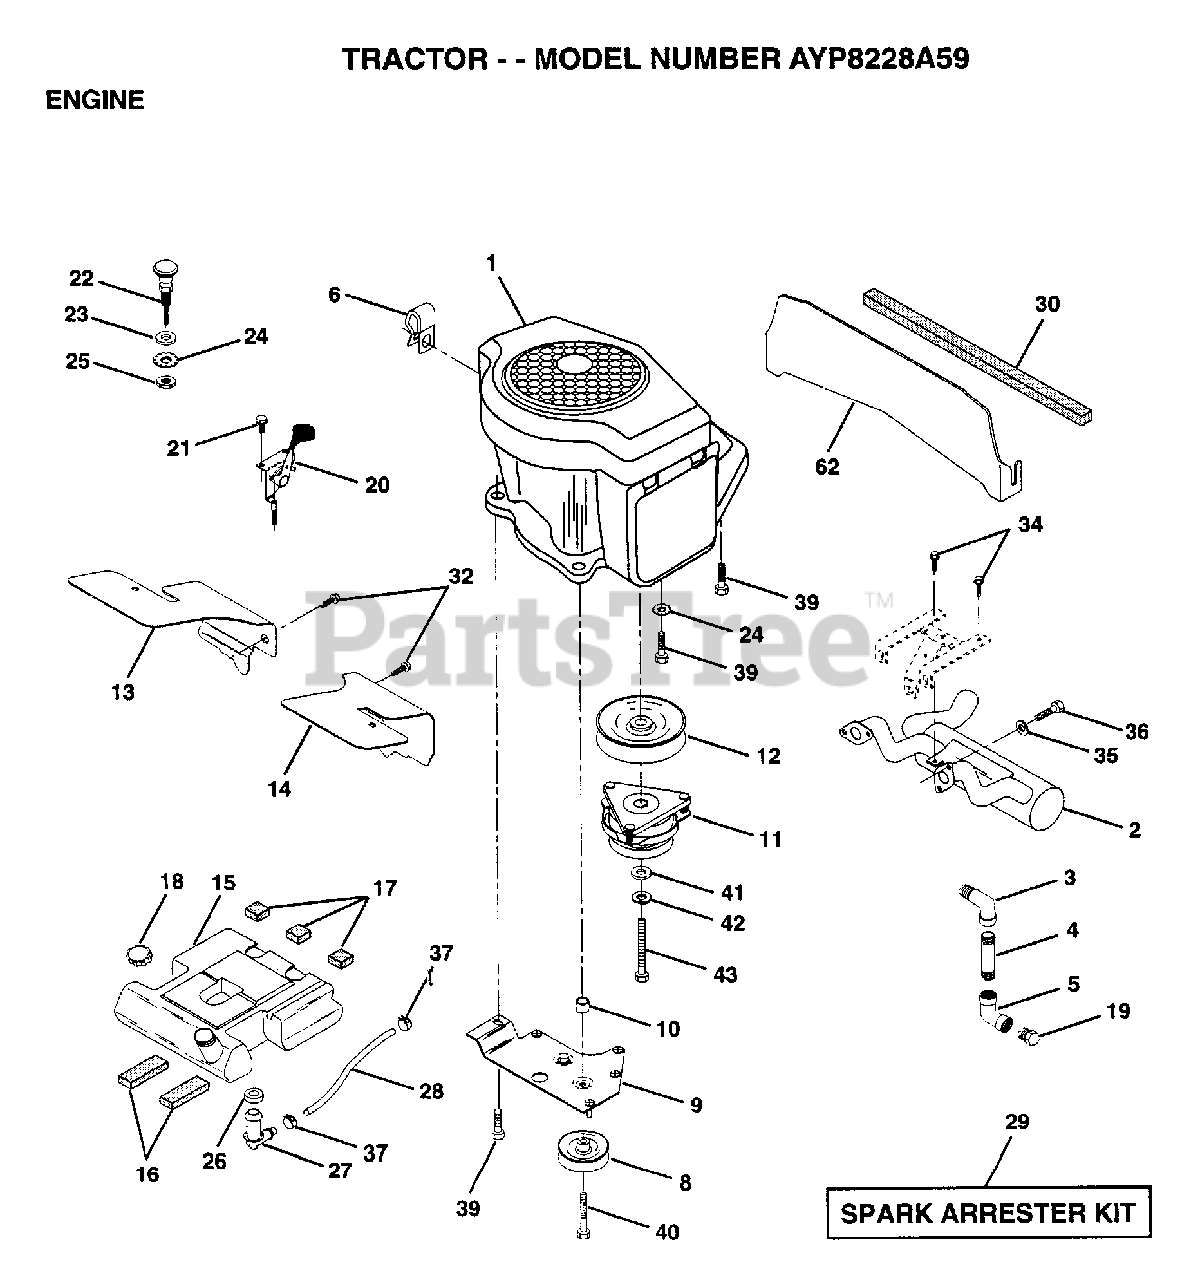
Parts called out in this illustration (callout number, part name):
2	MUFFLER.KOH.VCT.
3	STREET ELBOW LT
4	PIPE NIPPLE
5	ELBOW
6	CLAMP.TUBE.DBL.EN
10	BUSHING.
12	PULLEY.ENGINE.VGT
13	BAFFLE.AIR.LH.K
16	PAD IDLER TI
17	PAD-SPACER LT
18	CAP ASM FUEL
19	PLUG T
20	CONTROL THTL 37
21	CONTROL THTL 37
21	SCREW LT
22	"CONTROL.CHOKE.51"""
23	WASHER
24	LOCKWASHER
26	BUSHING OUTLET T
27	STEM.TANK.FUEL
29	SPARK ARREST KIT
32	SCREW LT
34	SCREW
35	LOCKWASHER
36	SCREW
37	HOSE CLAMP
39	SCREW LT
40	SCREW.3/8-16X3.25
41	WASHER
42	LOCKWASHER
62	SHIELD.HEAT.MUF
